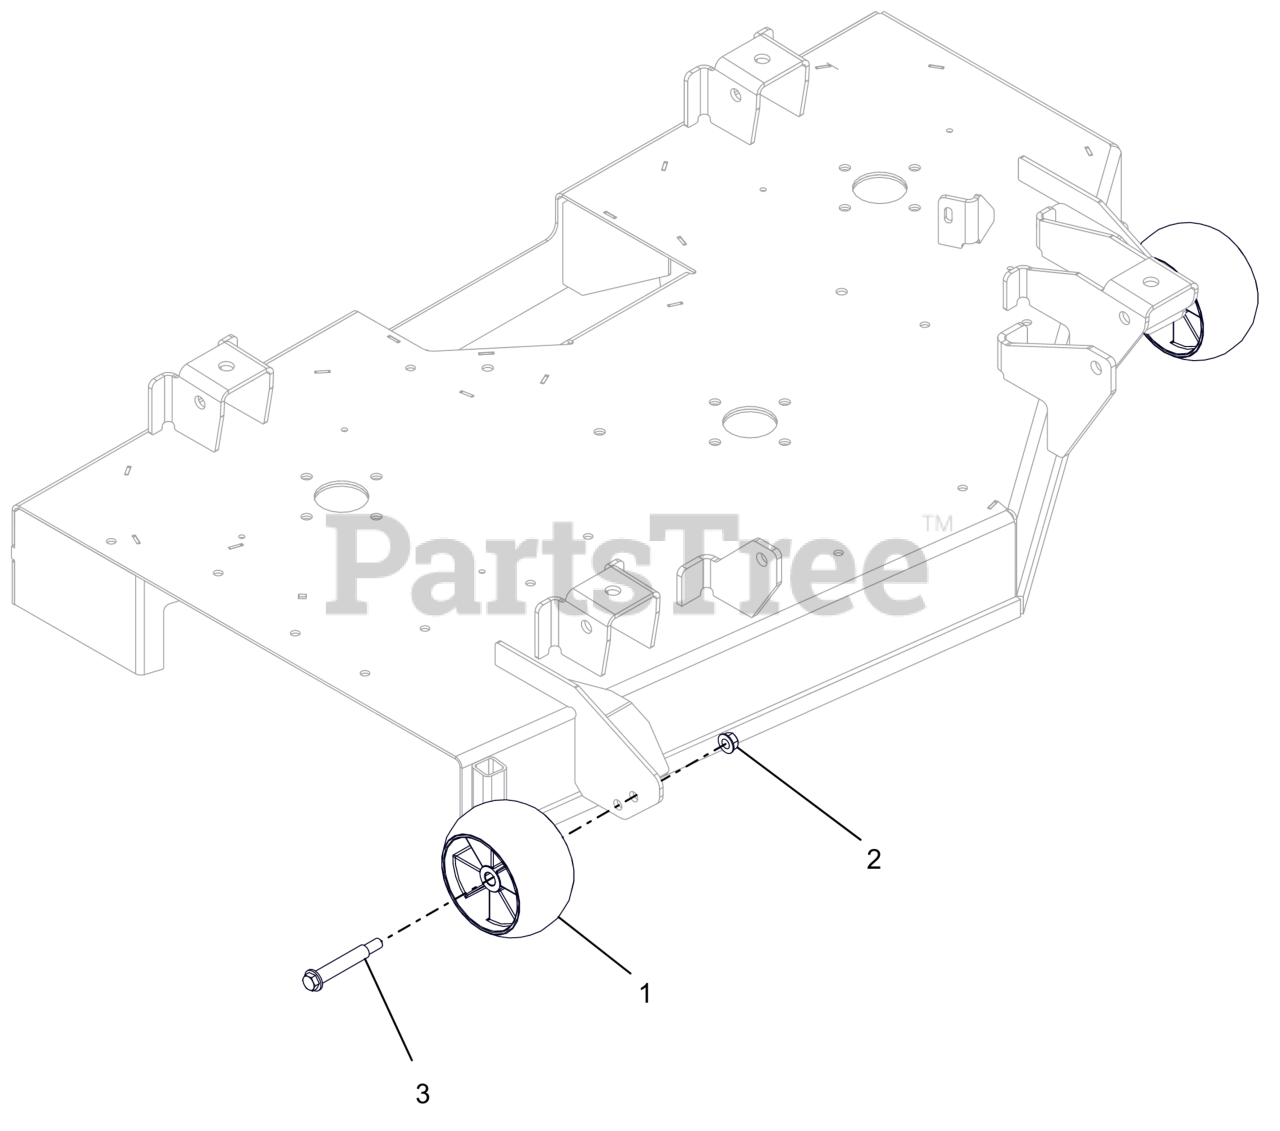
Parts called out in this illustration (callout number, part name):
1	ANTI-SCALP WHEEL - 5X OS
2	NUT-LK-CTR-FLG .375-16 GF ZCC
3	BLT-SHLDR .38-16X2.50 HWH G5
